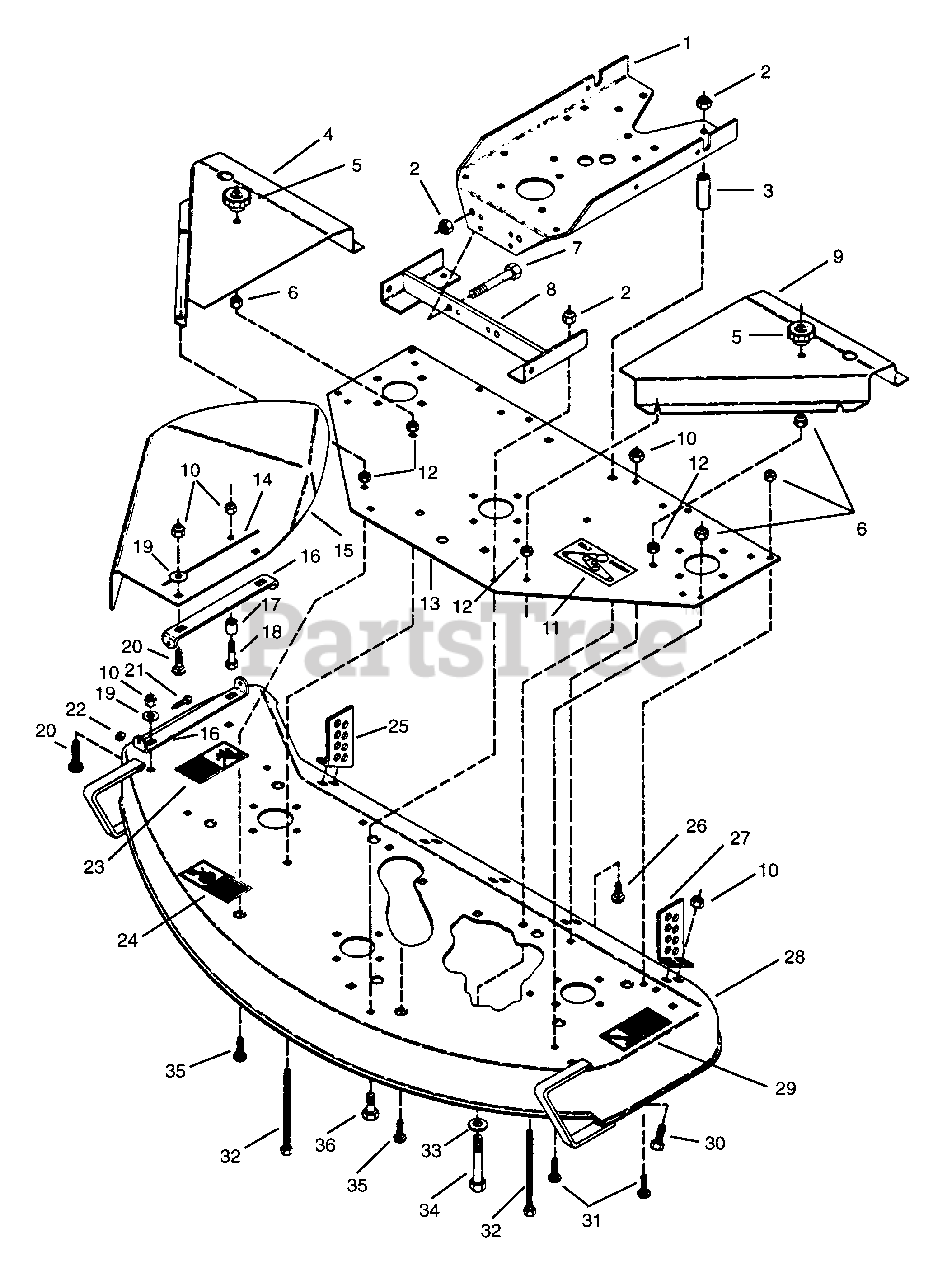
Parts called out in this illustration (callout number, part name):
1	Support, Gear Housing
2	Nut-Locking-Nylon .50-13 Grade 5
3	Spacer .510 x .840 x 2.437
4	Cover, Pulley Right Hand
5	Knob
6	Nut-Locking-Nylon .312-18 Grade 2
7	Bolt-Hex .50-13 x 1.375
8	Bracket, Height Adjustment
9	Cover, Pulley Left Hand
10	Nut-Locking-Nylon .375-16 Grade 2
11	Decal, Belt Installation
12	Nut-Jam .312-18
13	Plate, Support
14	Stripe
15	Shield, Safety External 50" Mower
16	Bracket, Chute
17	Bushing-Sleeve .407 x .625 x .750
18	Bolt-Hex .38-16 x 1.50 Grade 5
19	Washer-Flat-Steel .406 x .812 x .065
20	Bolt-Round Head Square Neck .38-16 x 1.0
21	Bolt-Hex .25-20 x .875
22	Nut-Locking-Nylon .250-20 Grade 2
23	Decal, Danger Hand
24	Decal, Warning Eye
25	Plate, Rear Adjustment
26	Bolt-Round Head Square Neck .375-16 x .75 Grade 1
27	Plate, Rear Adjustment
28	Weldment, 50" Mower Deck
29	Decal, Danger Foot
30	Bolt-Hex .38-16 x 1.25 Grade 5
31	Bolt-Round Head Square Neck .31-18 x .75 Grade 5
32	Bolt-Round Head Square Neck .31-18 x 3.5
33	Washer-Flat-Steel .531 x 1.062 x .095
34	Bolt-Hex .50-13 x 3.75
35	Bolt-Round Head Square Neck .31-18 x 1.0
36	Bolt-Hex .50-13 x 1.25 Grade 5
